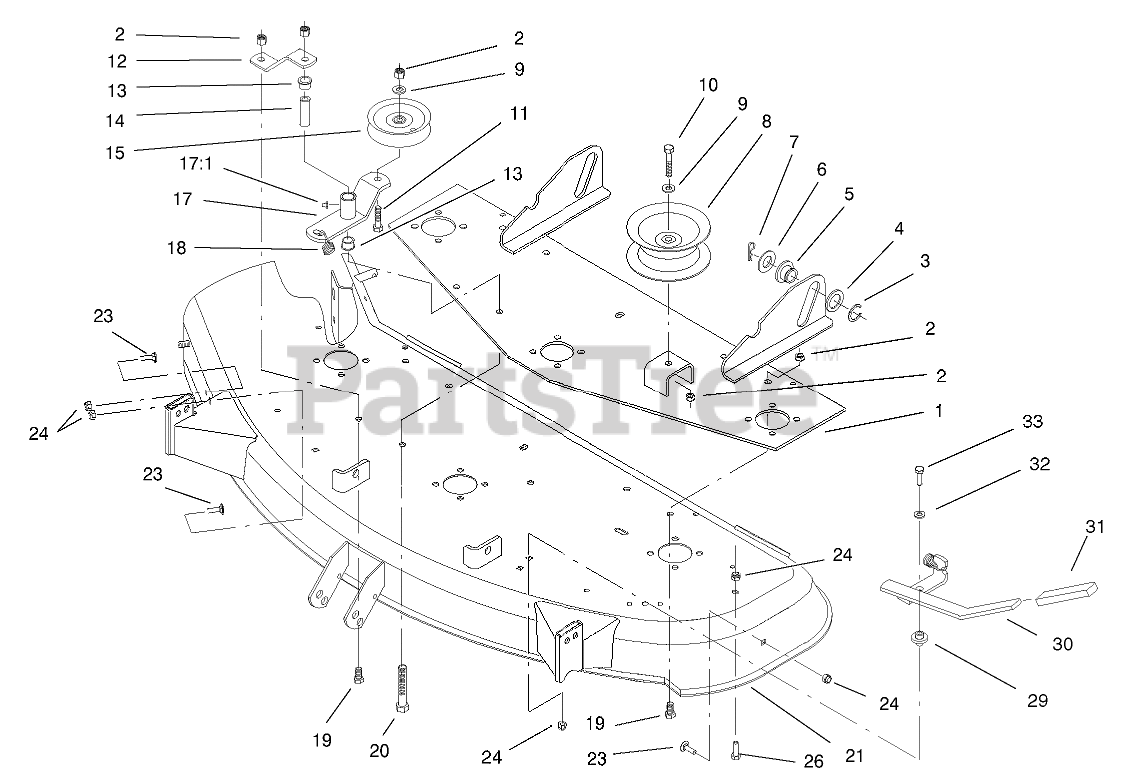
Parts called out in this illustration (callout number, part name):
1	SUPPORT-DECK
2	NUT-LOCK, NI
3	RING-RETAINING
4	WASHER
5	ROLLER-LIFT
6	WASHER-FLAT
7	PIN-HAIR
8	PULLEY-IDLER
9	WASHER-FLAT
10	SCREW-HH
11	SCREW-HH
12	STRAP-BRACE
13	BUSHING
14	SPACER
15	PULLEY-IDLER, FLAT
17	ARM - IDLER
17:1	FITTING-GREASE
18	SPRING - EXTENSION
19	SCREW-HH
20	SCREW-HH
21	48" DECK/DECAL ASM
23	SCREW-CARR
24	NUT-LOCK, NI
26	SCREW-CARR
29	SPACER-RACK, STEERING
32	WASHER-PLAIN
33	SCREW-HH
